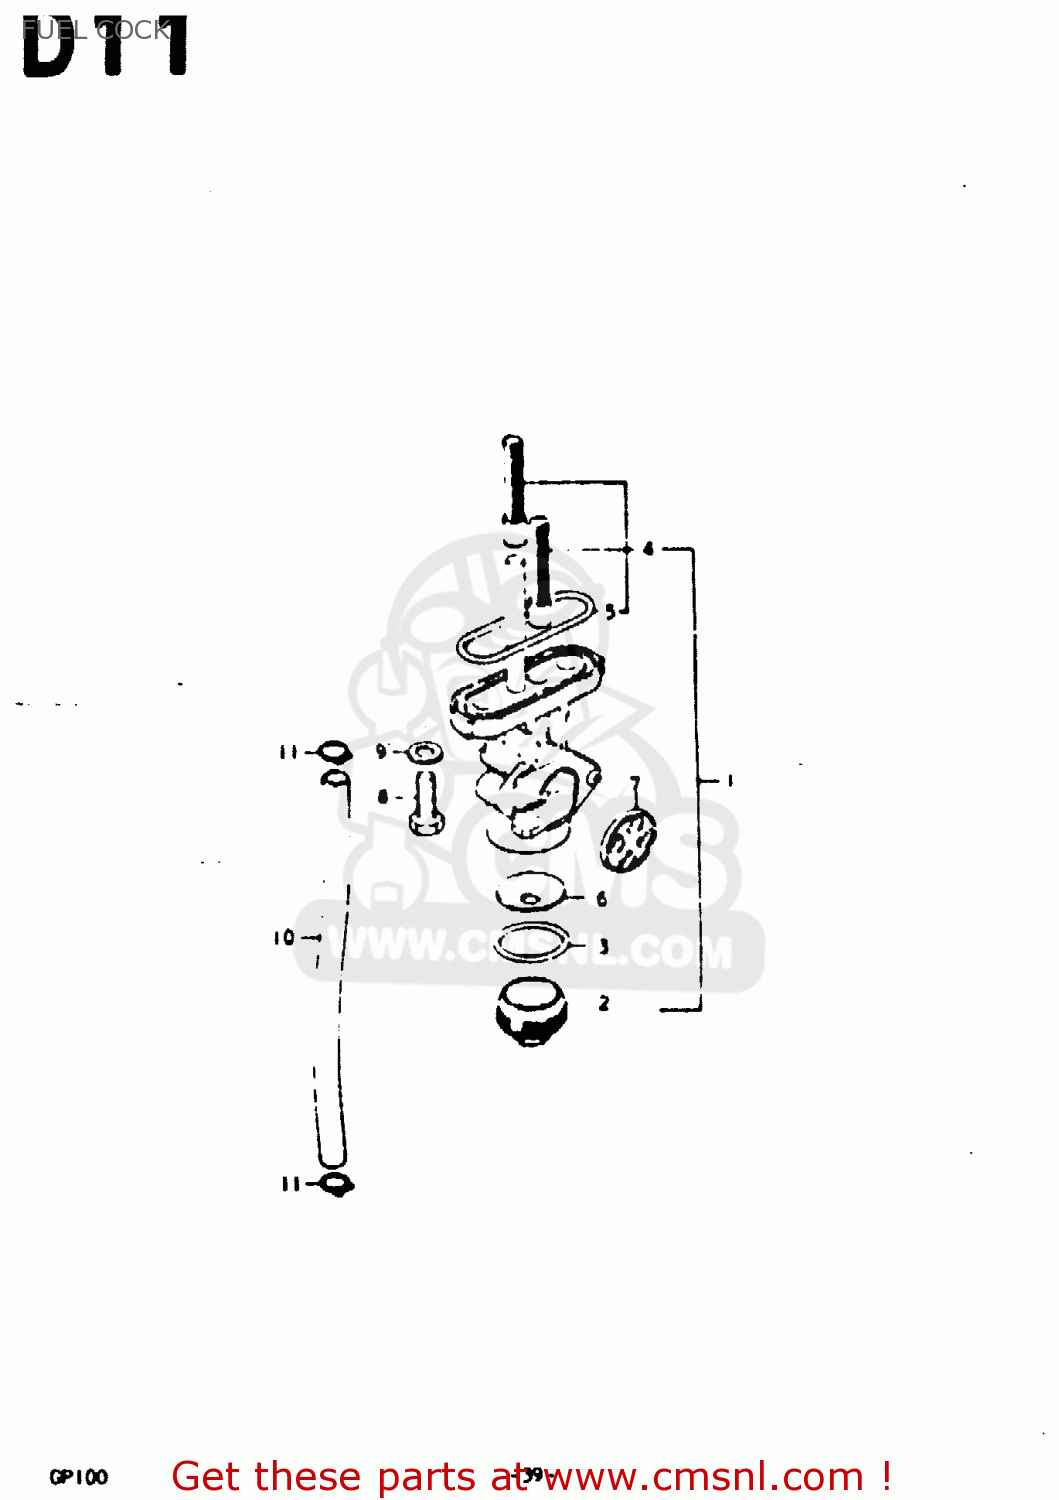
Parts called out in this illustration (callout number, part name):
1	COCK ASSEMBLY,FUEL
2	CUP,FUEL COCK
3	GASKET,FILTER (NAS)
4	FILTER SET,FUEL COCK
5	O RING,FUEL COCK
6	NET,STRAINER
7	GASKET,LEVER (NAS)
8	BOLT L:16
9	GASKET
10	HOSE
11	CLIP
